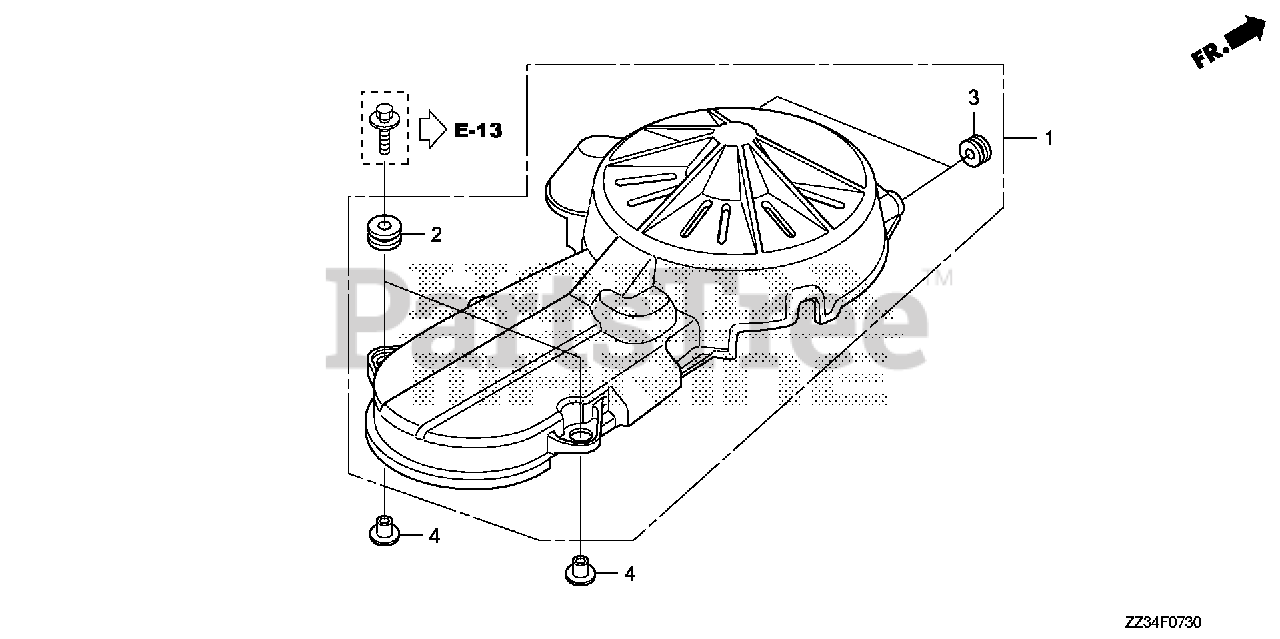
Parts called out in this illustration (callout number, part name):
1	COVER, ALTERNATOR
2	GROMMET, CASE (LOWER)
3	GROMMET, SIDE COVER
4	COLLAR, MODULE IGNITION CONTROL CASE (CDI)
